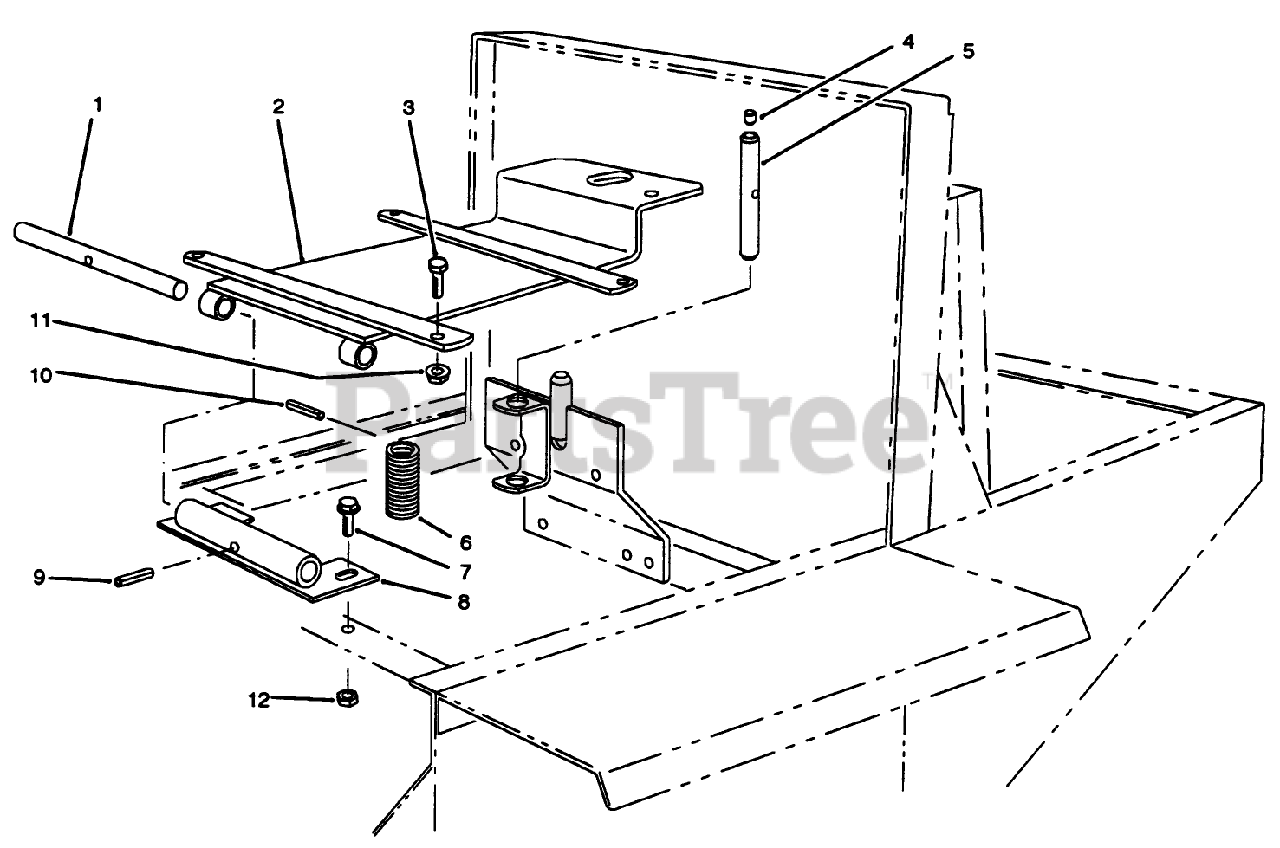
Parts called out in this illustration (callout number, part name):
1	SHAFT-PIVOT, SEAT
2	Seat Support
3	SCREW-HH
4	PIN-PEDAL
5	PIN-SWITCH, SEAT
6	COMP SPRING
7	SCREW-HHF
8	Pivot-Seat
9	PIN-ROLL, SLOTTED
10	PIN-ROLL, SLOTTED
11	NUT-HF
12	NUT-JAM
